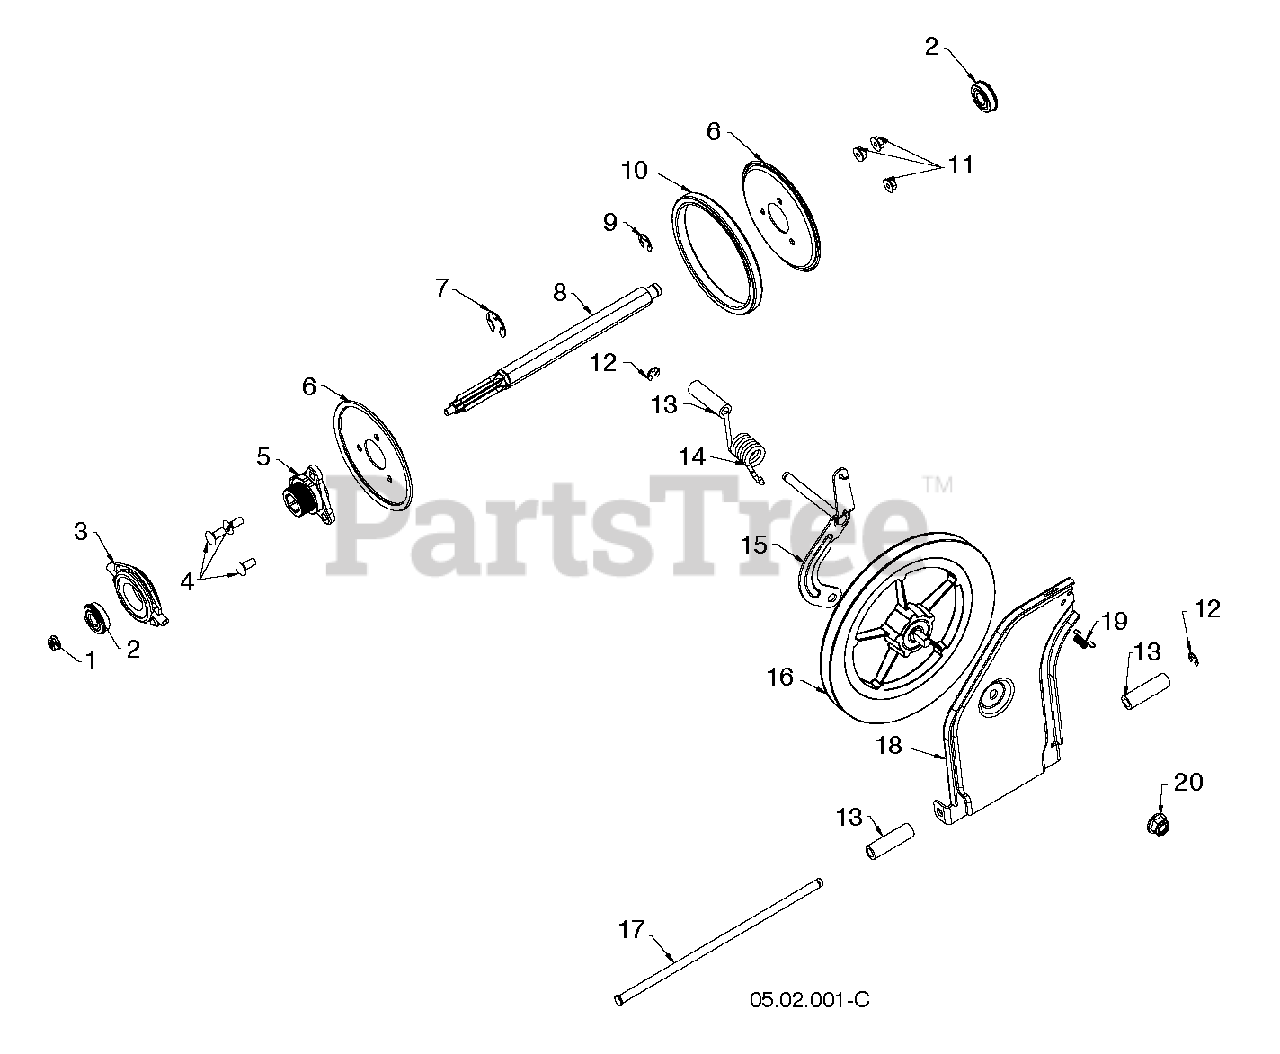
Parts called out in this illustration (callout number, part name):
1	Flange Hex Lock Nut, 5/16-18
2	Bearing, 9/16" Id. Snr
3	TRUNNION BEARING ASSY
4	BOLT.5/16-18.
5	HUB.RUBBER.WHEEL
6	Wheel Plate, Rubber Black
8	Reduction Shaft, 7T
9	Retaining Ring
10	Ring, Rubber
11	NUT.LOCK.5/16-18
13	SPACER YOKE, TORSION SPRING
14	Drive Torsion Spring
15	Bracket Yoke Weldment
16	Friction Disc Combo Pulley
17	ROD.TIP.PLATE
18	PLATE SWING FRICTION PULL_MS
19	SPRING LATCH
20	NUT, 1/2-13 HEX FLG NYLOC ZD
